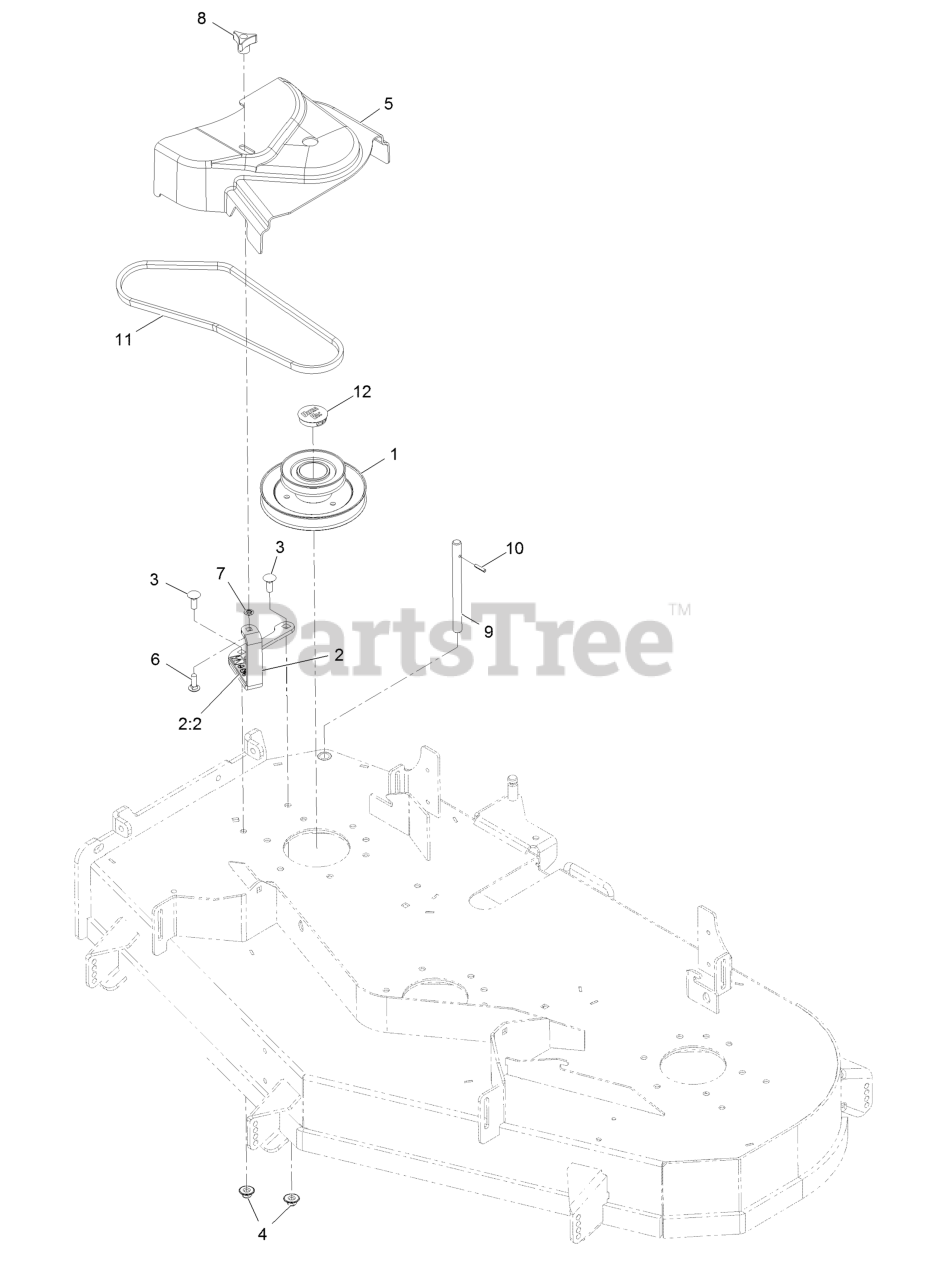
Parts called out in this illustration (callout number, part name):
1	JACKSHAFT,UV DRIVE 524 SP
2	ASM-CVR BRKT W/DECAL
2:2	DECAL-DANGER
3	BOLT-CARR
4	Nut-Nyloc 3/8-16 Flg
5	COVER-BELT, UV 52
6	BOLT-CARR
7	RING-RETAINING, BOLT
8	KNOB-3 PRONG
9	SHAFT-CATCHER, GRASS
10	PIN-ROLL
11	BELT, BLOWER 52"DECK
12	PLUG, BLACK NYLON 1.75
